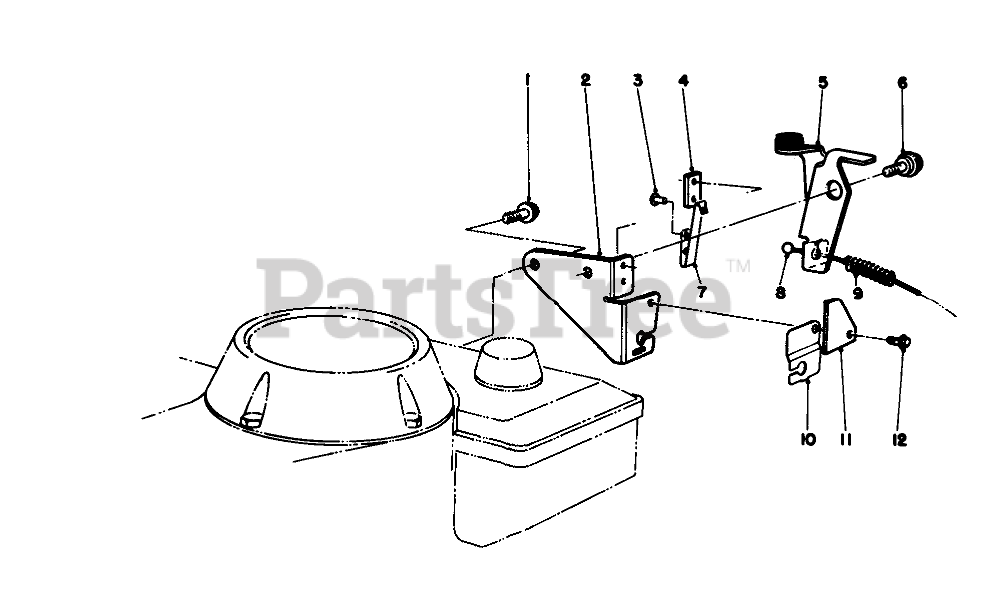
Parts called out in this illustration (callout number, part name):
1	THO FORM SCREW M6 X 1
2	Plate-Mounting Assembly (Incl. Ref. #3, 4&7)
3	RIVET-PLASTIC
4	Strap-Insulation
5	BRAKE PLATE ASM
6	Screw-Shoulder
7	STRAP-GROUND
8	BRAKE CABLE
9	SPRING-COMPRESSION
10	CABLE CLAMP
11	STOP-GROUND STRAP
12	SCREW
